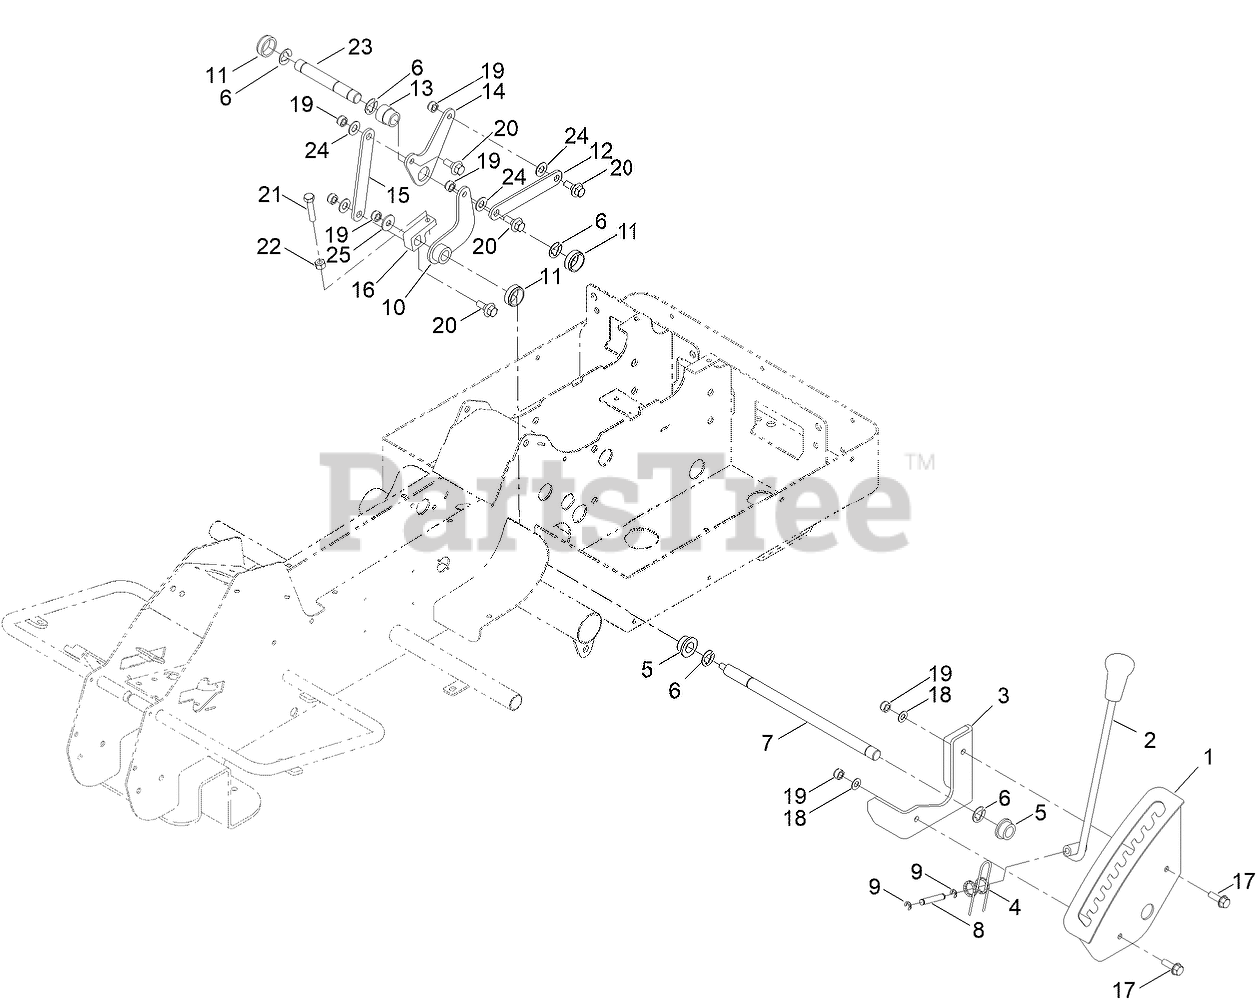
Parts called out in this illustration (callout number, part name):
1	HOC PLATE ASM
2	HOC LEVER ASM
3	BRACKET, HOC LEVER
4	SPRING, HOC LEVER
5	BUSH, HOC SHAFT
6	CLIP, HOC SHAFT
7	HOC SHAFT
8	SHAFT, HOC LEVER
9	CLIP, HOC LEVER SHAFT
10	HOC ROTATION PLATE ASM (SMALL)
11	BUSH, HOC SHAFT
12	SHORT PLATE, HOC
13	BUSH, SHORT SHAFT
14	PLATE, ROTATION LARGE (HOC)
15	LONG PLATE, HOC
16	ADJUSTMENT, HOC
17	SCREW-HHF
18	WASHER-PLAIN
19	NUT-HEX, NI
20	FLANGE BOLT, SHOULDER
21	BOLT
22	PLAIN NUT
23	SHORT SHAFT, HOC LEVER
24	WASHER-PLAIN
25	WASHER
